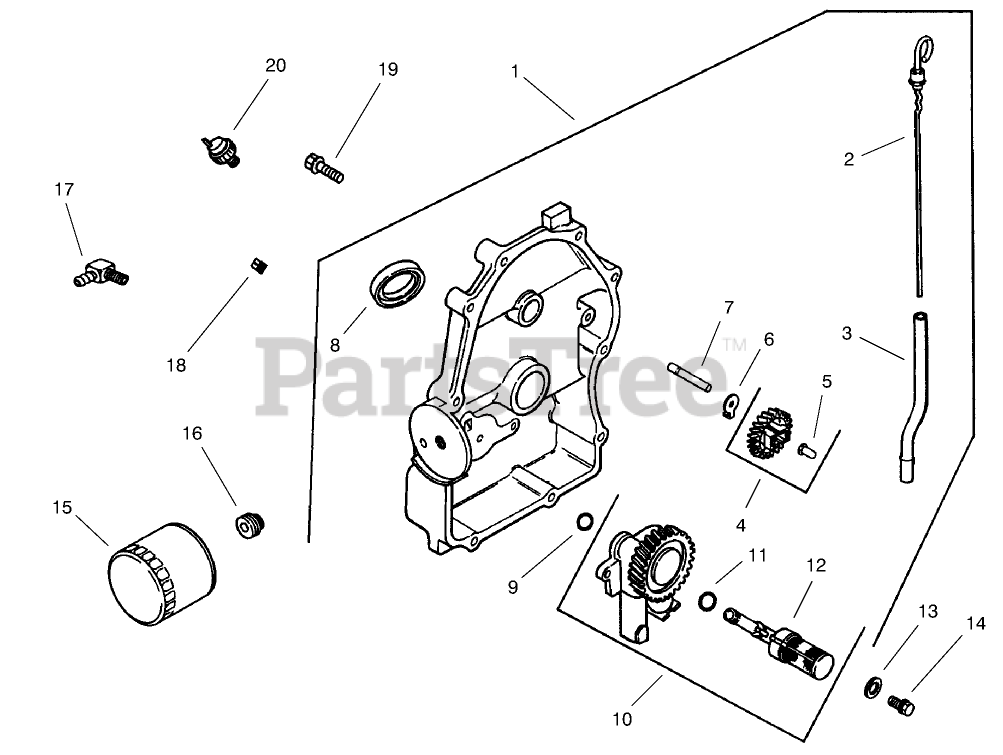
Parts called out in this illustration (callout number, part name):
1	Plate, closure assembly (Includes 2-12)
2	Dipstick
3	Tube-Dipstick
4	Kit-Governor Gear Assembly (Incl. Ref. #7)
5	Pin-Governor
6	Tab-Locking
7	Shaft-Govenor Gear
8	Seal-Oil
9	O Ring
10	Oil pump assembly (Includes 11, 12)
11	ORing
12	Pick Up-Oil
13	Washer
14	Screw
15	Filter-Oil
16	Nipple-Oil Filter
17	Connector
18	Plug
19	Screw
20	Switch-Oil Pressure
